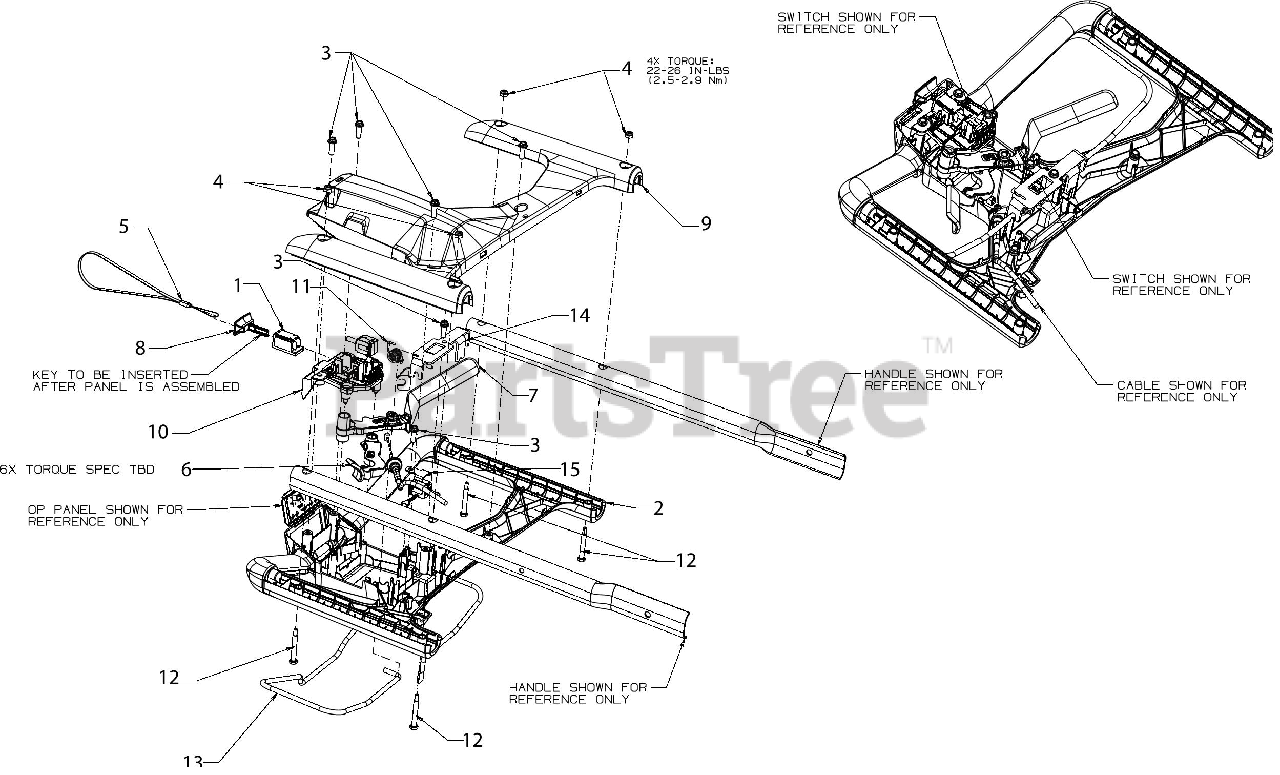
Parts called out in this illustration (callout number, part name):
1	KEY RECEPTICAL ASSEMBLY
2	UPPER HANDLE PANEL ASSEMBLY
5	KEY STRAP CORE
6	CONTROL LEVER (LH)
7	CONTROL LEVER (RH)
8	KEY CORE
9	LOWER HANDLE PANEL
10	KEY RECEPTICLE BRACKET
11	TORSION SPRING
12	SHOULDER SCREW .25:1.63:#10-24:.32
13	BAIL CONTROL
15	BAIL SWITCH BRACKET
